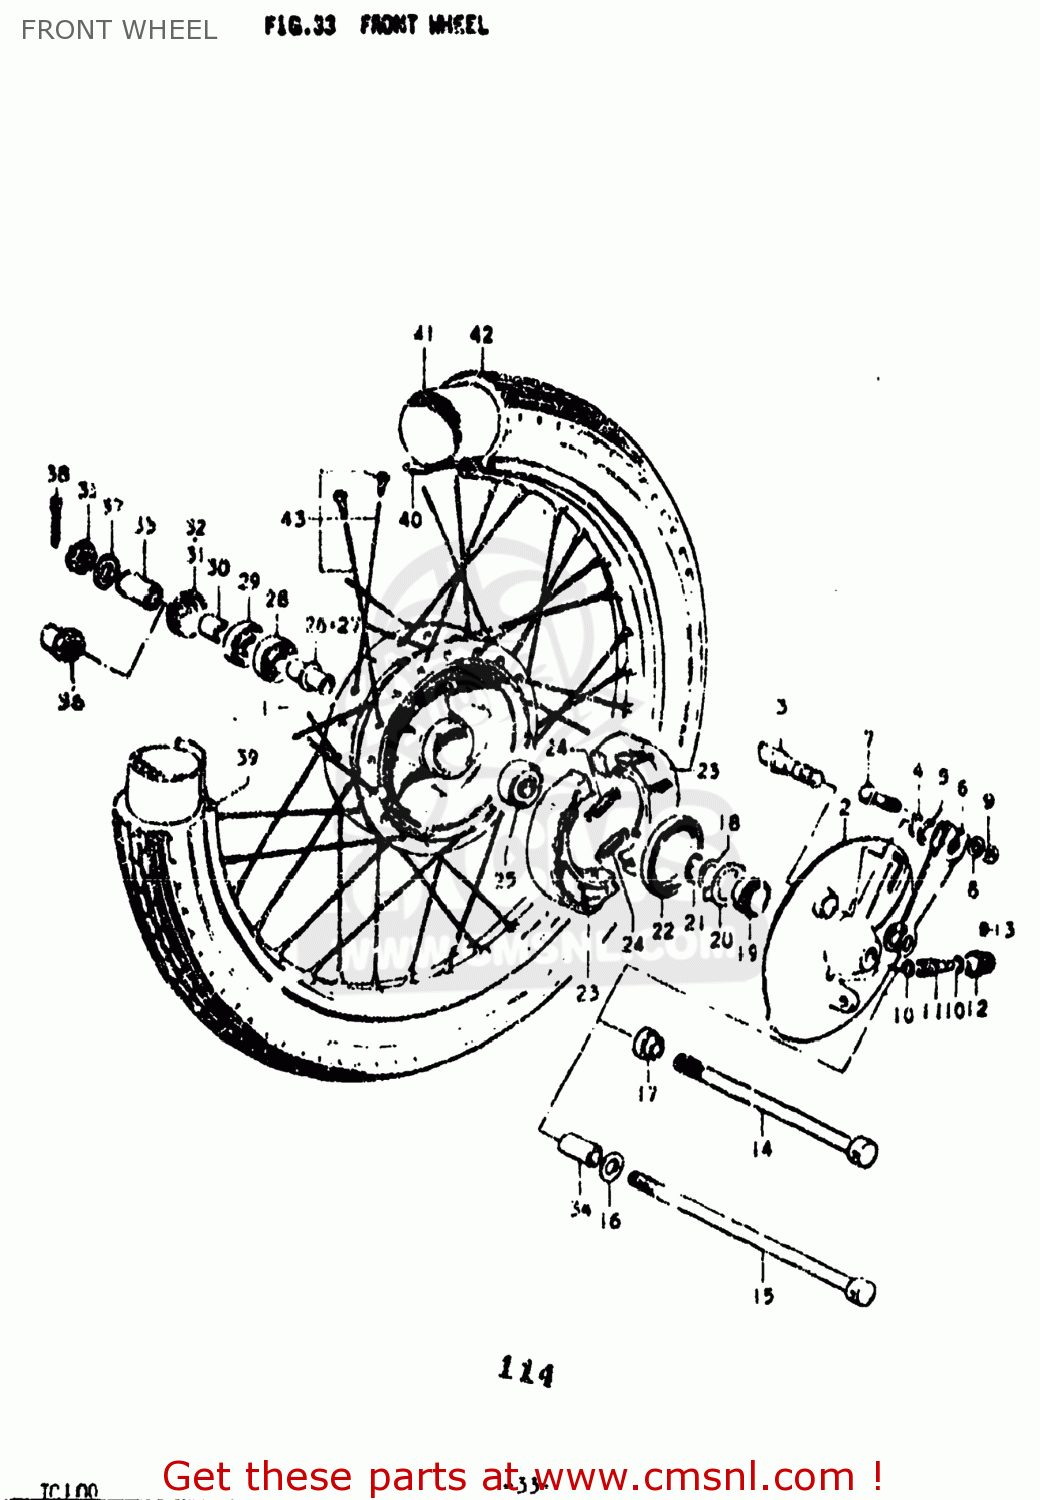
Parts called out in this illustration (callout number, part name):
1	HUB,FRONT
2	PANEL,FRONT HUB
3	CAM,FR BRAKE
4	O RING(D:2.5,ID:11.4)
5	WASHER(12.5X20X1)
6	LEVER,FRONT BRAKE CAM
7	BOLT
8	WASHER
9	NUT
10	WASHER (5.1X9X0.4)
11	PINION,SPEEDOMETER
12	BUSH,METER GEAR OUTER
13	SCREW
14	AXLE,FRONT
15	AXLE,FRONT
16	WASHER
17	SPACER,FRONT AXLE,LEFT
18	WASHER(18.5X24X1)
19	GEAR,SPEEDOMETER
20	DRIVER,SPEEDOMETER GEAR
21	CIRCLIP
22	SEAL,OIL(48X62X7)
23	SHOE,BRAKE
24	SPRING(L:34)
25	BEARING, LH
26	SPACER (12.6X19X52)
27	SPACER,FRONT HUB BEARING
28	BEARING
29	OIL SEAL
30	SPACER
31	DUST SEAL,FRONT HUB DRUM
32	DUST SEAL,FRONT HUB DRUM
33	SPACER (12X20X44)
34	SPACER (12X20X41)
35	NUT 12MM
36	NUT,FRONT AXLE
37	WASHER
38	COTTER PIN
39	RIM,FRONT WHEEL
40	PROTECTOR,WHEEL,INNER
41	TUBE 2.75-19 070-483MM
42	TIRE,FRONT
43	SPOKE SET,FRONT
